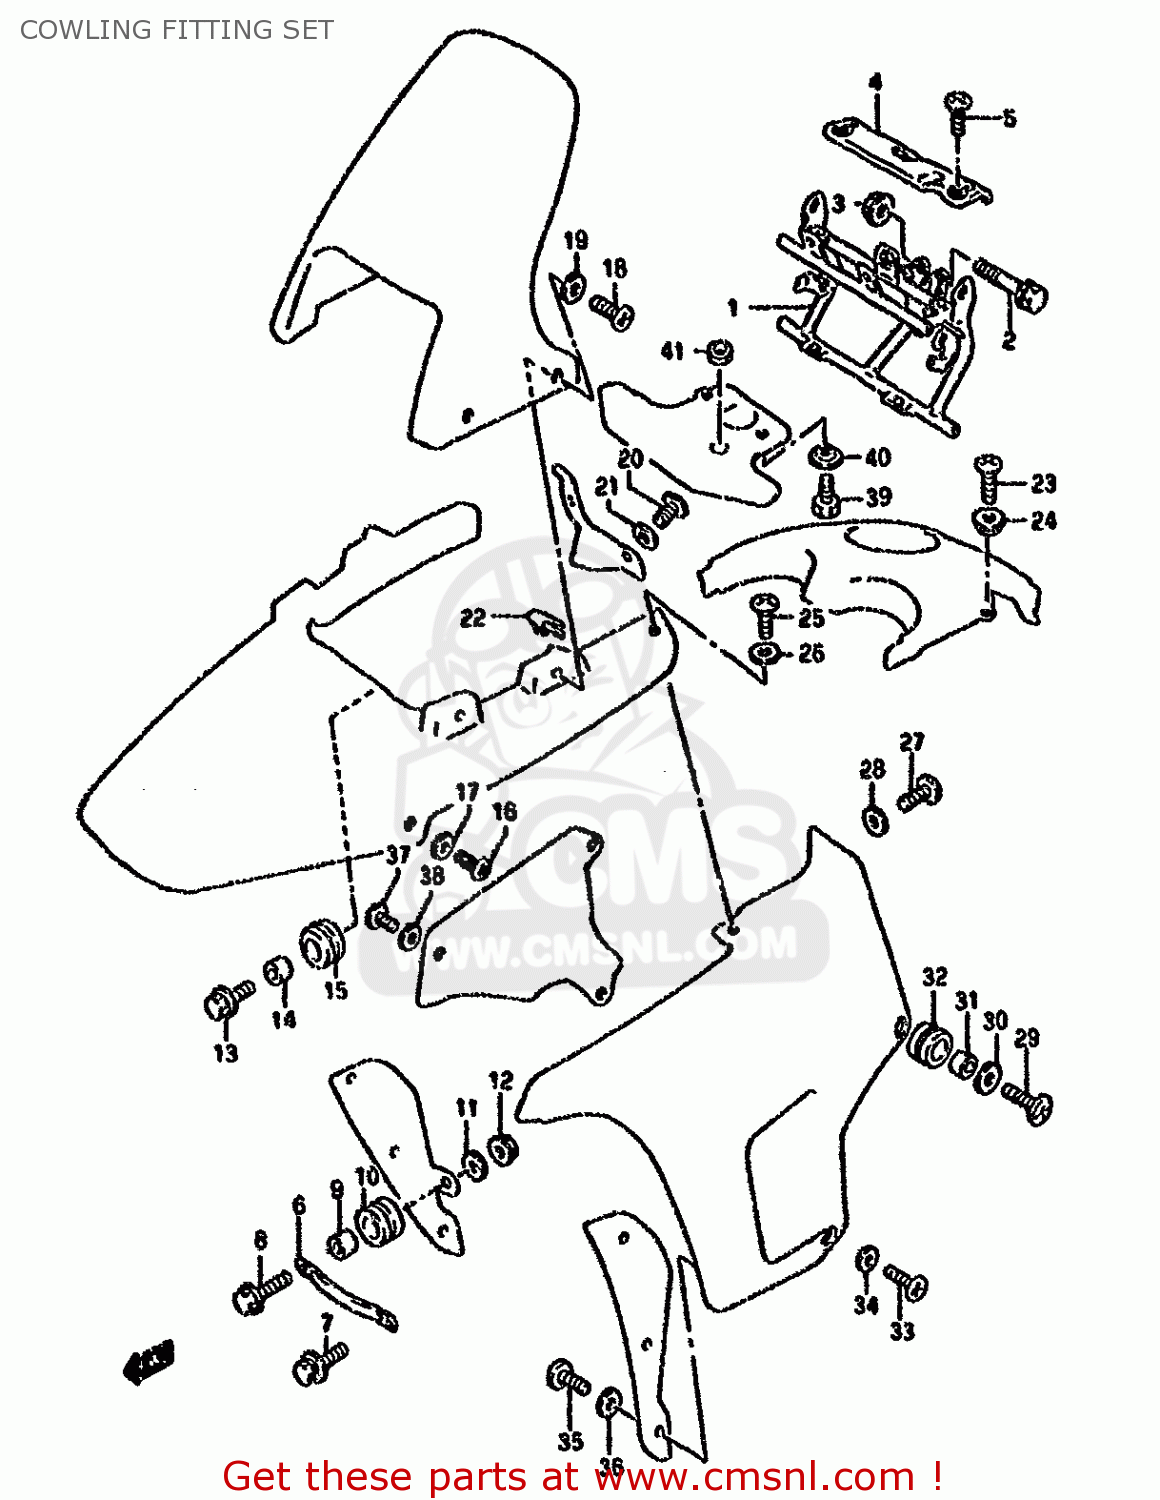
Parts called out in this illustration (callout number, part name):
1	BRACE,COWLING
2	BOLT
3	NUT
4	COVER,COWLING BRACE
5	SCREW 6X12
6	BRACE,COWLING SIDE
7	BOLT
8	BOLT
9	SPACER(6.1X9X7.5)
10	CUSHION
11	WASHER(6.5X20X1.6)
12	NUT
13	BOLT(6X25)
14	SPACER (6.1X9X10)
15	CUSHION
16	SCREW(5X16)
17	WASHER(7X13X0.6)
18	SCREW
19	WASHER(5.2X11X1)
20	SCREW(5X12)
21	WASHER
22	NUT,HEADLAMP HOUSING,UPPER
23	SCREW(5X12)
24	WASHER(5.2X14X1.5)
25	SCREW(5X16)
26	WASHER(7X13X0.6)
27	SCREW(5X16)
28	WASHER
29	SCREW(6X20)
30	WASHER(6.5X18X1)
31	SPACER (6.1X9X10)
32	CUSHION
33	SCREW(5X14)
34	WASHER(5.2X14X1.5)
35	SCREW
36	WASHER
37	SCREW
38	WASHER
39	BOLT
40	WASHER
41	GROMMET
